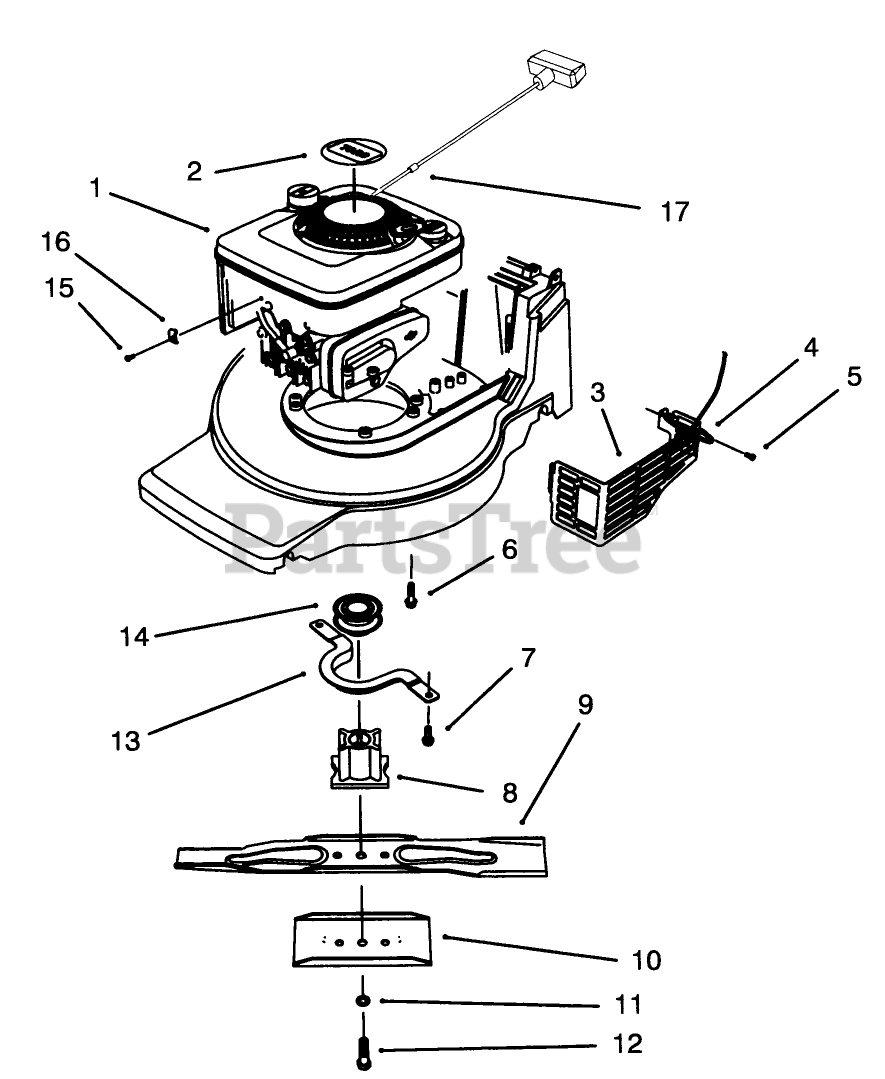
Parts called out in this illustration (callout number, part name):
1	Engine-BS Quantum
3	SHIELD - MUFFLER
4	TIE-CABLE
6	SCREW-HWH
7	SCREW-HWH
9	Blade
10	Stiffener Blade
11	WASHER-LOCK
12	BOLT-BLADE
14	PULLEY-DRIVE, ZONE START
15	CLAMP SCREW F/W ENGINE
16	CLAMP-CASING
17	STOP-ROPE
